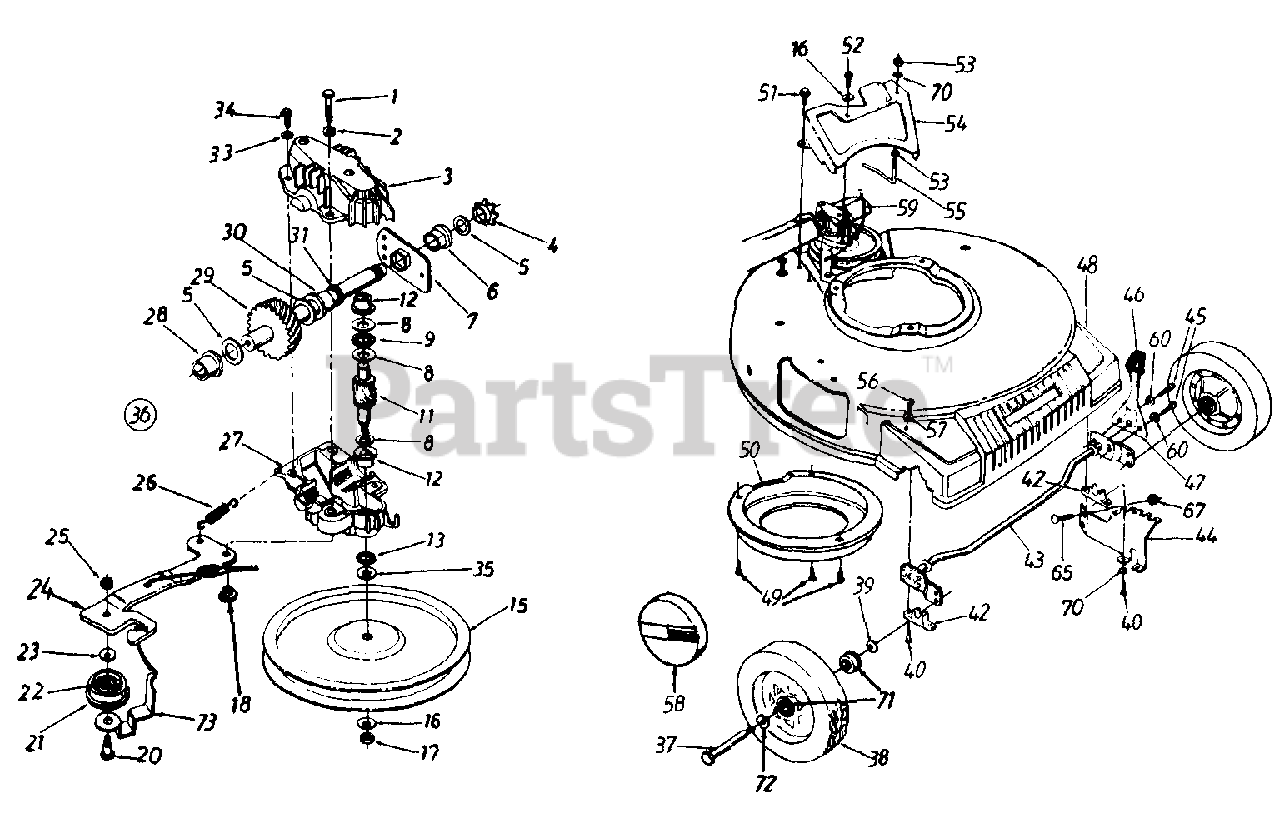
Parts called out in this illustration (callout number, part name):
1	Hex Patch Bolt 1/4-20 x 1.25"
2	L-Wash. 1/4" I.D.
3	Upper Hsg. Half
4	#48 Sprocket 7 T x 1/2 Pitch
5	Fl-Wash. 5/8" I.D. x .030
6	Hex Flange Brg. .631" I.D
8	Thrust Wash. .382" I.D. x .70" O.D.
9	Thrust Bearing .375" I.D. x .812" O.D.
11	11 Tooth Pinion Shafts
12	Flange Bearing
15	Fl-Pulley 5.06" O.D.
16	Bell-Wash. .265" I.D. x .75"
17	Hex L-Nut 1/4-28 L.H. Thd.
18	Shld. Spacer .375" Dia. x .170
20	Shld. Bolt .375" Dia. x .40"
21	Fl-Idler Plastic 1.50" Dia.
22	Needle Brg. .375" x .31
23	Bell-Wash. .265" I.D. x .75"
24	Idler Brkt. Assy.
25	Hex Patch L-Nut 1/4-28 Thd.
26	Extension Spring 1.12" Lg.
27	Lower Hsg. Half
28	Flange Bearing .566 Dia.
30	Flange Bearing .629 Dia.
31	Oil Seal .625 Dia.
34	Hex B-Tap Scr. #10 x .75"
35	Hex Washer .26" x .88"
36	Transmission Comp.
37	Front Axle Bolt
38	Wheel Assy. Comp.
39	Bell-Wash. .380" I.D. x .88
40	Hex Wash. Hd. Scr. 1/4 x 1" Lg.
42	Block Bushing
45	Hex TT-Tap Scr. 1/4-20 x .38"
46	Knob
47	Spring Lever
48	Plastic Front End
49	Hex B-Tap Scr. 1/4" x .50"
52	Hex Wash. Hd. B-Tap Scr.1/4 x .62" (Spec)
53	Hex Nut 1/4-20 Thd.
56	Torx Truss Hd. Scr. 5/16 x .75"
57	Bell-Wash. .345" I.D. x .88"
58	Hub Cap
59	S.P. Cable
60	External L-Wash. 1/4" I.D.
65	Carr. Bolt 1/4-20 x .5" Lg.
67	Hex Flange L-Nut 1/4-20 Thd.
70	L-Wash. 1/4" I.D.
71	Wheel Bearing
72	Wave Washer
